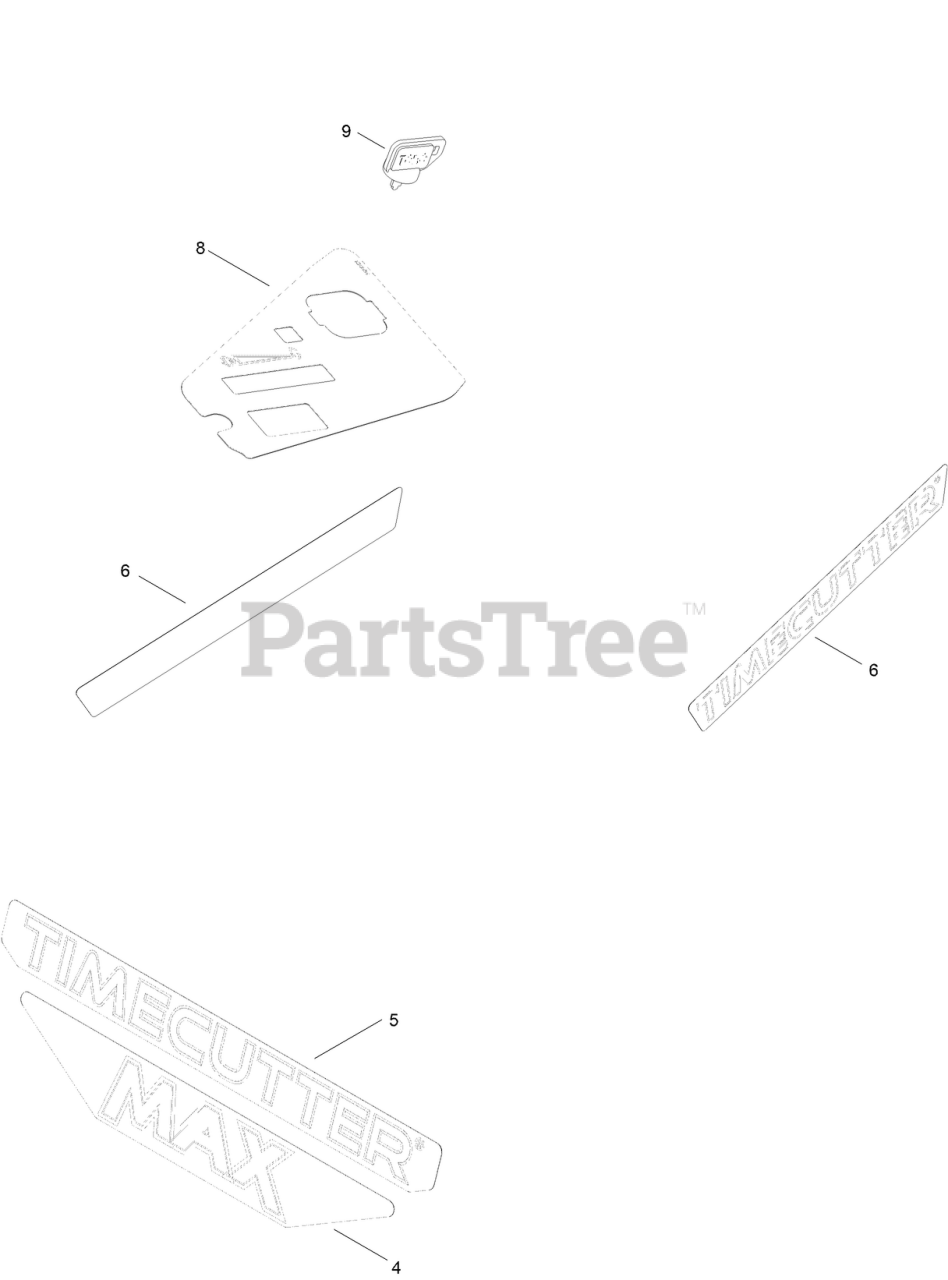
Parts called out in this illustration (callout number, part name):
4	DECAL-MAX
5	DECAL-TIMECUTTER
6	DECAL-TIMECUTTER
8	DECAL - CONTROL PANEL W/OUT HOUR METER
9	KEY-IGNITION
